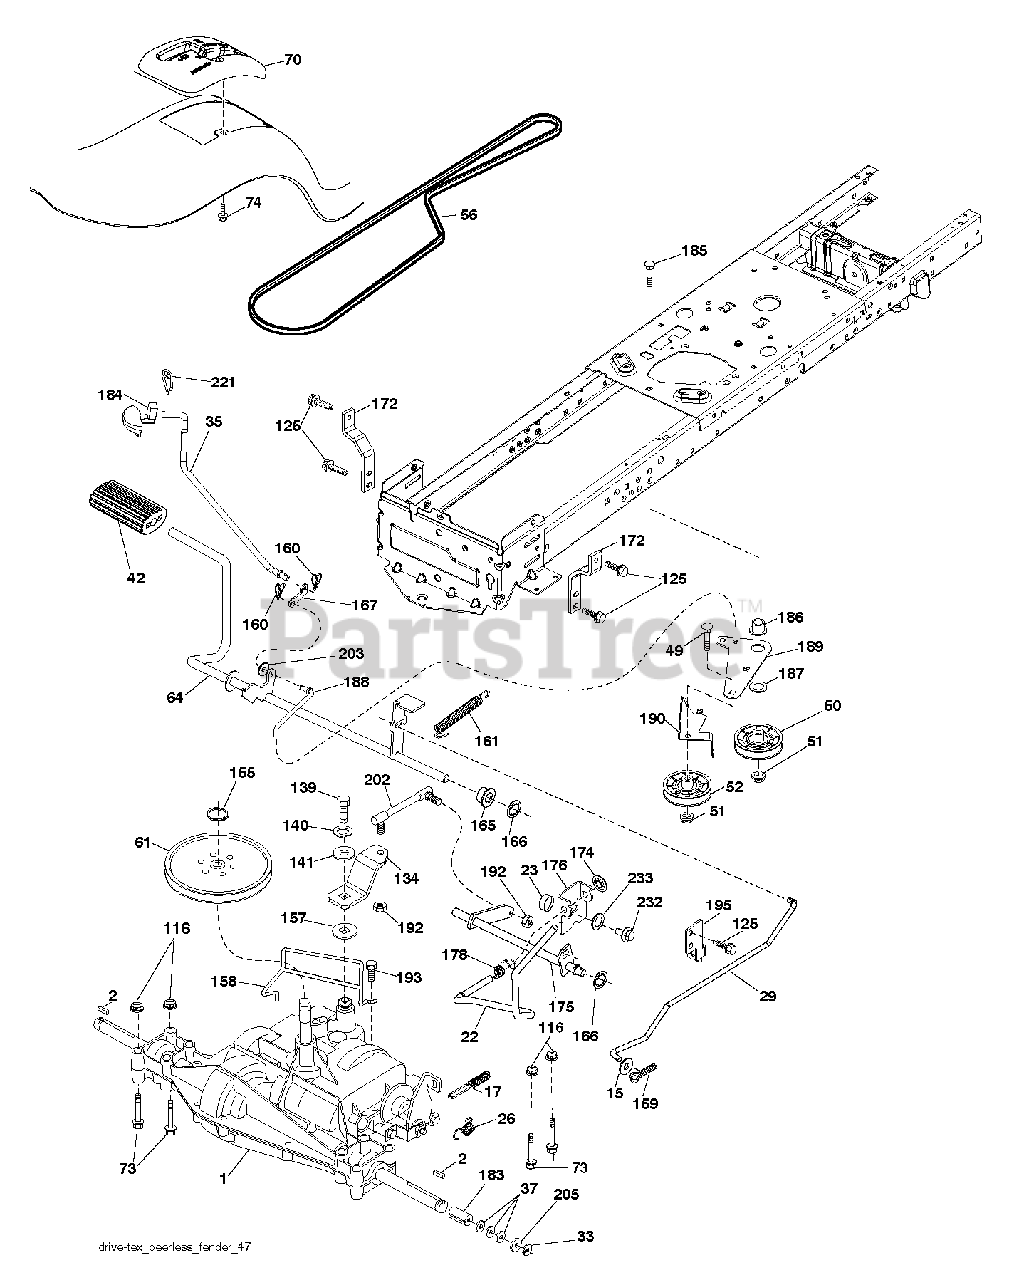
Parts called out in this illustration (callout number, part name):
2	SQUARE KEY
17	SPRING.BRAKE.PEERLESS.TEX
22	ROD.SHIFT.FENDER.TLT.2006
23	KNOB T (1/2-HOLE)
26	SPRING.BRAKE.RTN.GR.DR
29	ROD.BRAKE.PEERLESS
33	E-RING LT
35	ROD.BRAKE.PARKING.LT.T
49	BOLT
50	IDLER.FLAT.910.OFFSET
51	NUT LOCK FLG 3/8-16 UNC
52	IDLER.V-GROOVE.910.OFFSET
56	V-BELT.TRACTOR.DRIVE.P
61	PULLEY TRANS
64	SHAFT.ASM.PEDAL.BRAKE.
70	CONSOLE.SHIFT.STL.6SP.BLACK.T
74	SCREW.HI-LO.CONSOLE
116	NUT LOCK HEX FLANGE 5/16-18
125	SCREW
134	ARM SHIFT
139	Bolt, 1/4-20 unf Grade 8 w/Patch
140	LOCKWASHER
141	WASHER LT
155	RETAINING RING LT
157	WASH-SHFT PLT LT
158	KEEPER.PMS.18/20.D4365
159	COTTER PIN
160	RETAINER CLIP
161	SPRING, RETURN LT
165	BUSHING.SHAFT.BRAKE.HAND
166	NUT.PUSH.625
167	LATCH.BRAKE.SPRING
172	STRAP.TRQ.LH.GEAR.DRIV
174	NUT.PUSH.500.2006
175	SHAFT ASM SHIFT
176	ARM.CLEVIS.ROD.SHIFT
178	SPRING.SHIFT.GT2006
183	SPACER AXLE
184	HANDLE.PARKING.BRAKE.LTTEX.667
186	SPACER.RETAINER
187	WASHER 12/32X2X10GA
188	LINK.CLUTCH.GROUND.DRIVE
189	BELLCRANK.GROUND.DRIVE.TEX.
190	KEEPER.BELLCRANK.DRIVE
192	NUT LOCK CENTER 1/4 -28 FNTHD
193	SCREW 5/16"
195	BRKT.ROD.BRAKE.PEERLES
202	LINK.SHIFT.PMST.18" (SPG1286)
203	WASHER
221	RETAINER.SPRING.CLIP.H
232	BOLT FIN HEX 7/16-14 X 1
233	WASHER SERRATED
